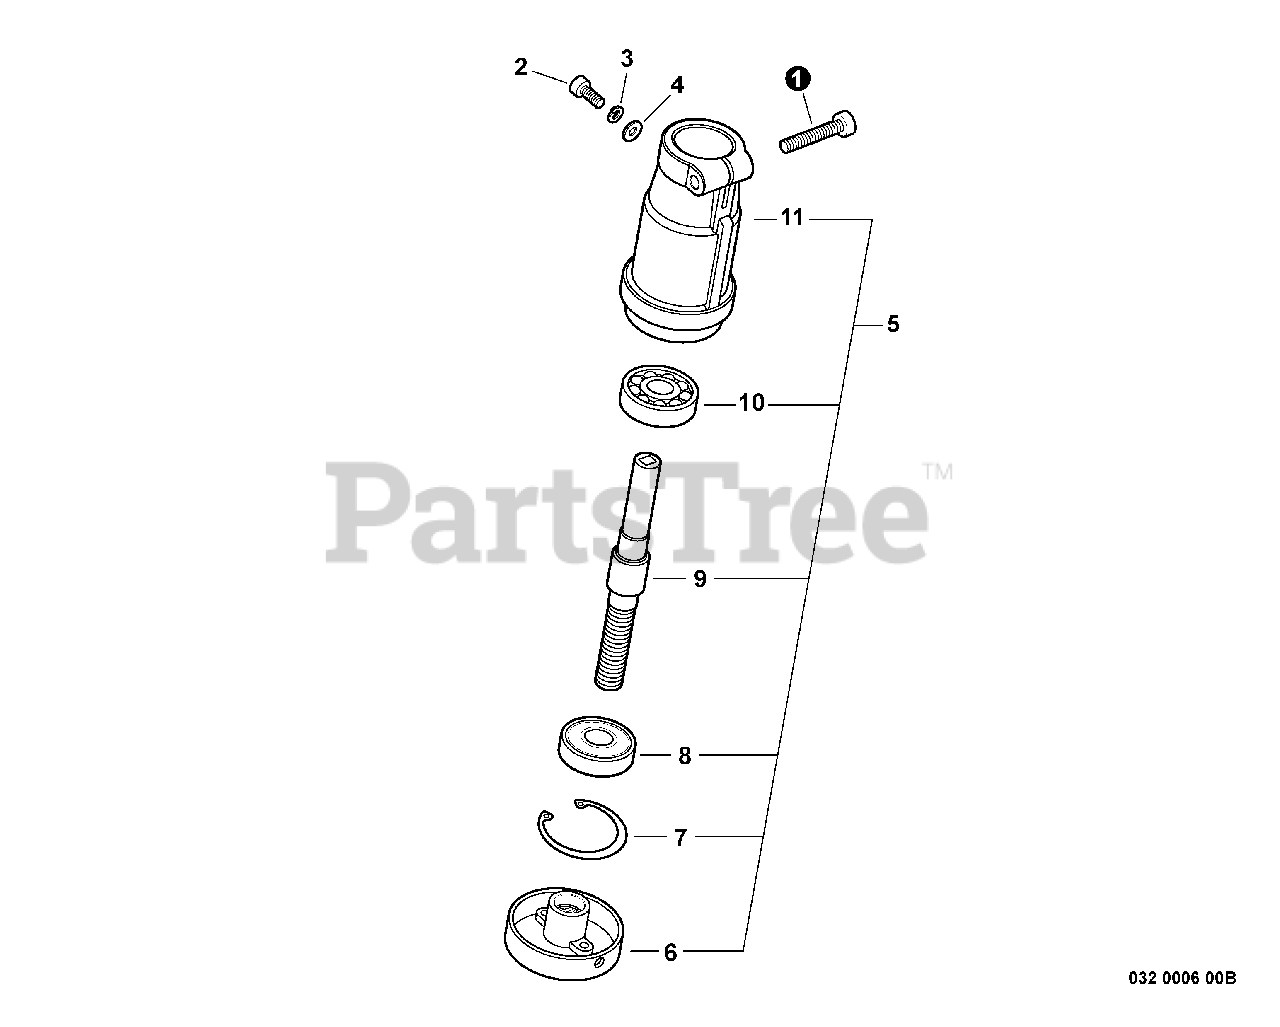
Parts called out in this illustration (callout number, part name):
1	BOLT, TORX 5×25
2	BOLT, TORX 4×10
3	WASHER, SPRING 4 MM
4	WASHER 4 MM
5	GEAR CASE ASSY
6	PLATE, ADAPTOR - UPPER
7	E-RING 30
8	BEARING, BALL 6200
9	SHAFT, GEAR
10	BEARING, BALL 6200
11	CASE, GEAR
